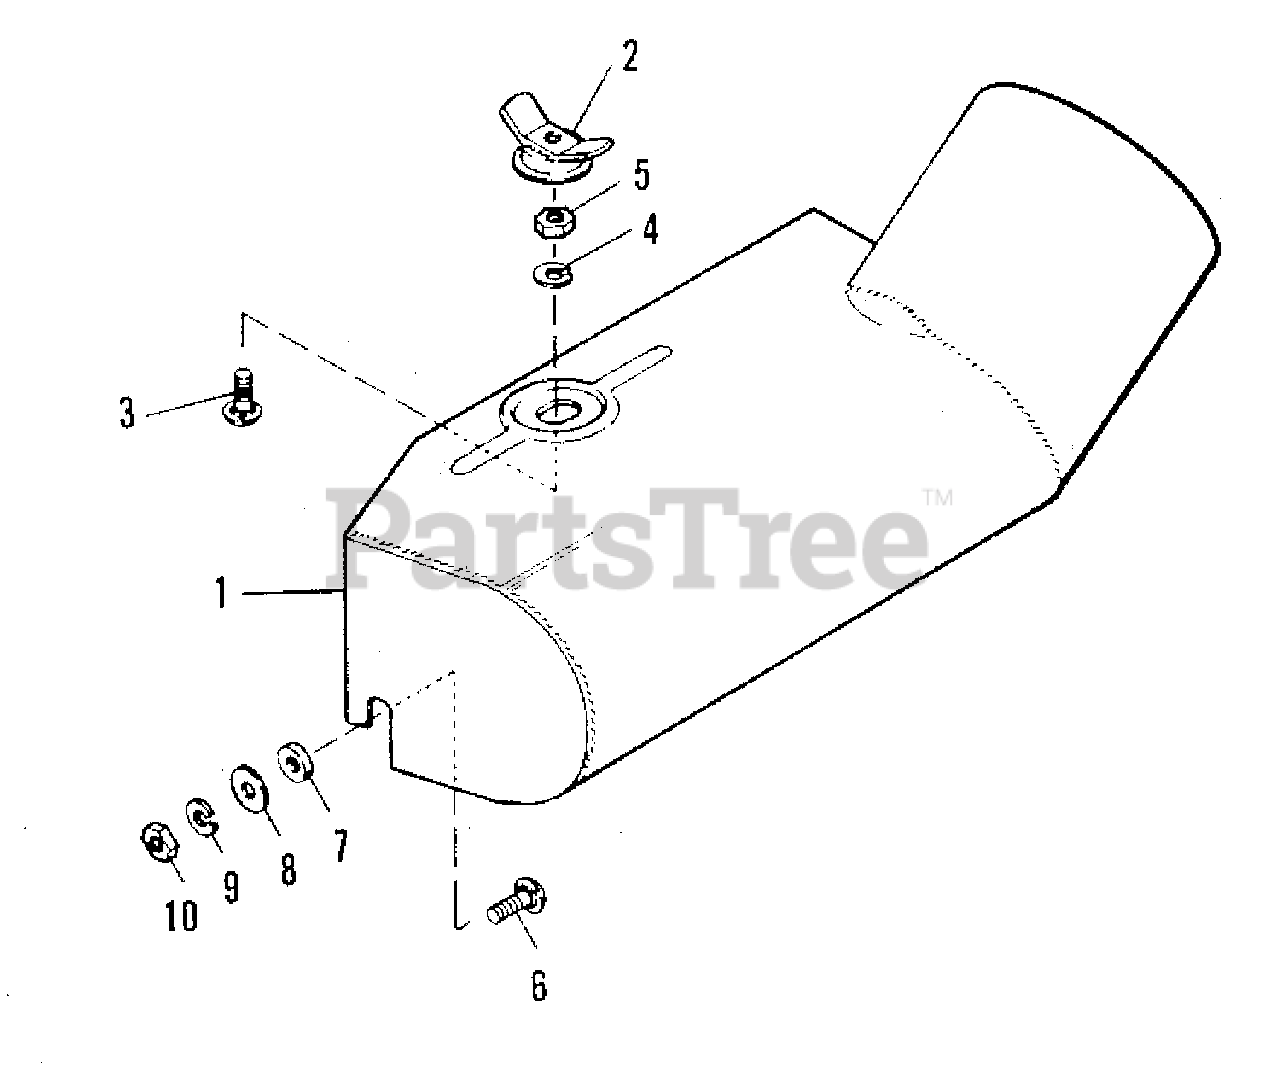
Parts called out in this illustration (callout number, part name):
1	ADAPTER ASSEMBLY
2	NUT ASSEMBLY
3	CARRIAGE BOLT, 3/8"-16 x 1"
4	LOCKWASHER, 3/8"
5	NUT, Hex Full, 3/8"-16
6	CARRIAGE BOLT, 3/8"-16 x 1-1/4"
9	LOCKWASHER, 3/8"
10	NUT, Hex Full, 3/8"-16
